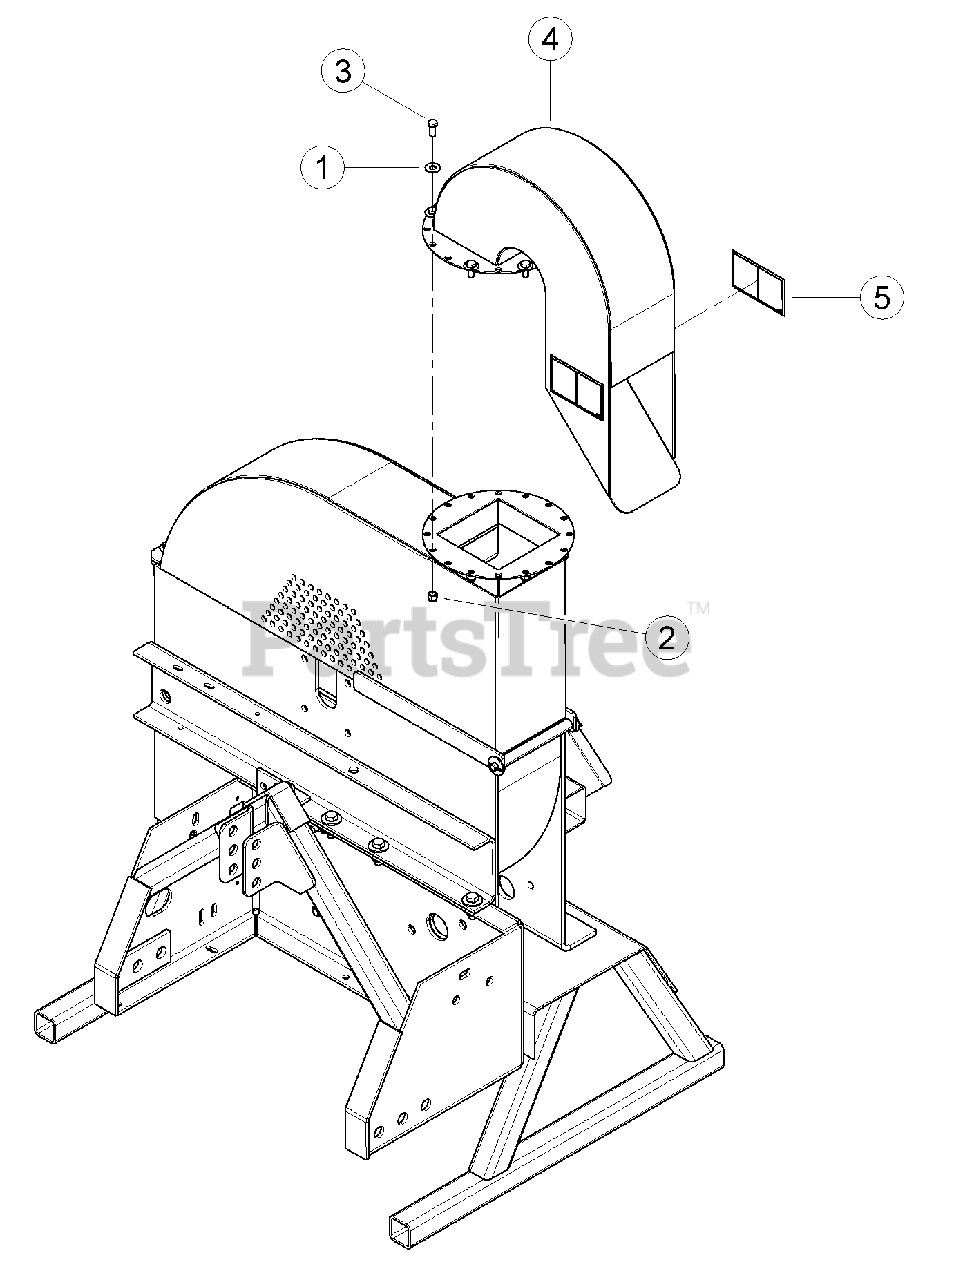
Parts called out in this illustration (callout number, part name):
1	WASHER, 3/8 FLAT ZP
2	NUT, 3/8 NE NYLOCK ZP
3	BOLT, 3/8 X 7/8 HEX HD GR5
4	ASSEMBLY, DISCHARGE CHIPPER
5	DECAL, BLADE DANGER ISO
